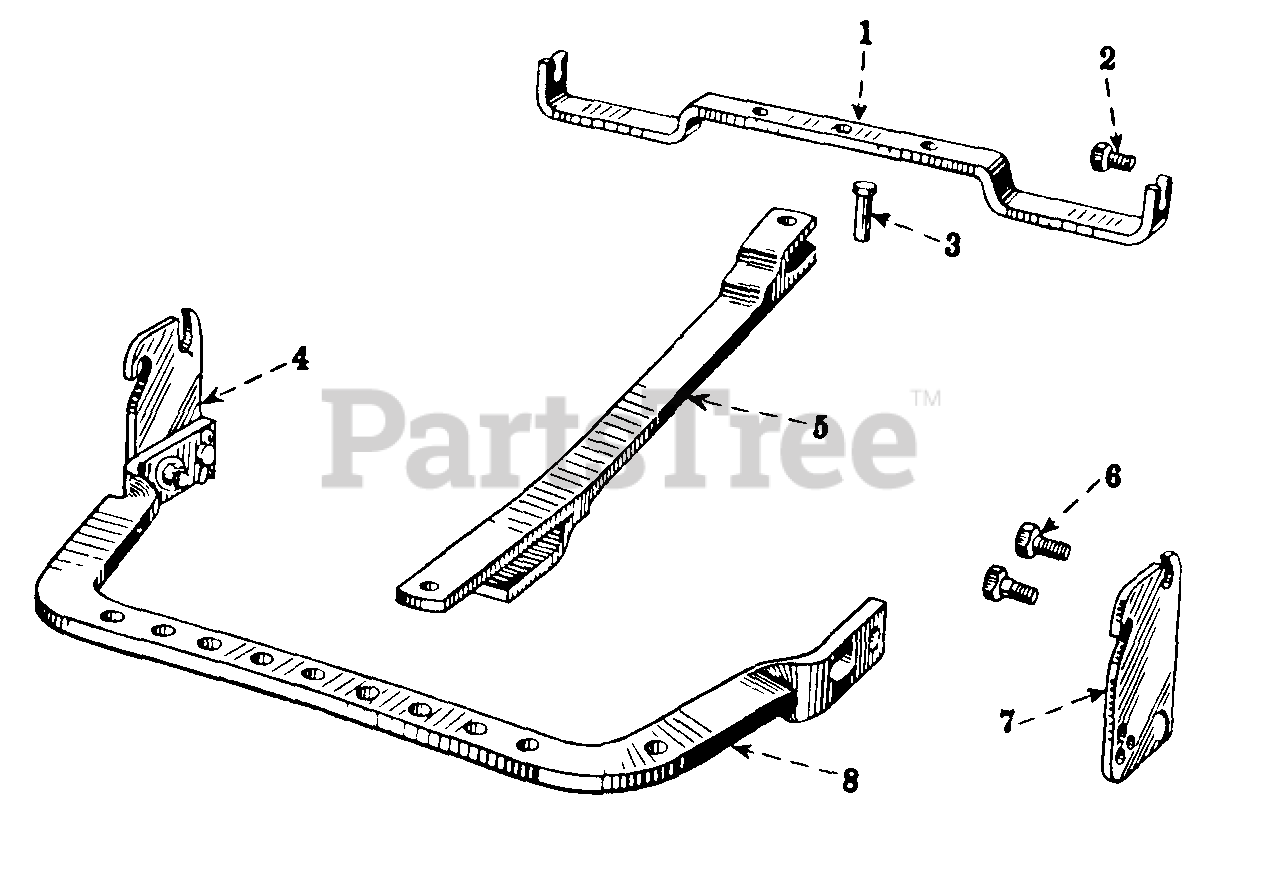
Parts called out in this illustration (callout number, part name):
1	BAR, SWINGING DRAWBAR ANCHOR
2	BOLT, SWINGING DRAWBAR ANCHOR BAR
3	PIN, SWINGING DRAWBAR PIVOT
4	BRACKET ASSY, QUICK ATTACHABLE DRAWBAR LH
5	DRAWBAR ASSY, SWINGING
6	BOLT, DRAWBAR BRACKET
7	BRACKET ASSY, QUICK ATTACHABLE DRAWBAR RH
8	DRAWBAR, QUICK ATTACHABLE
